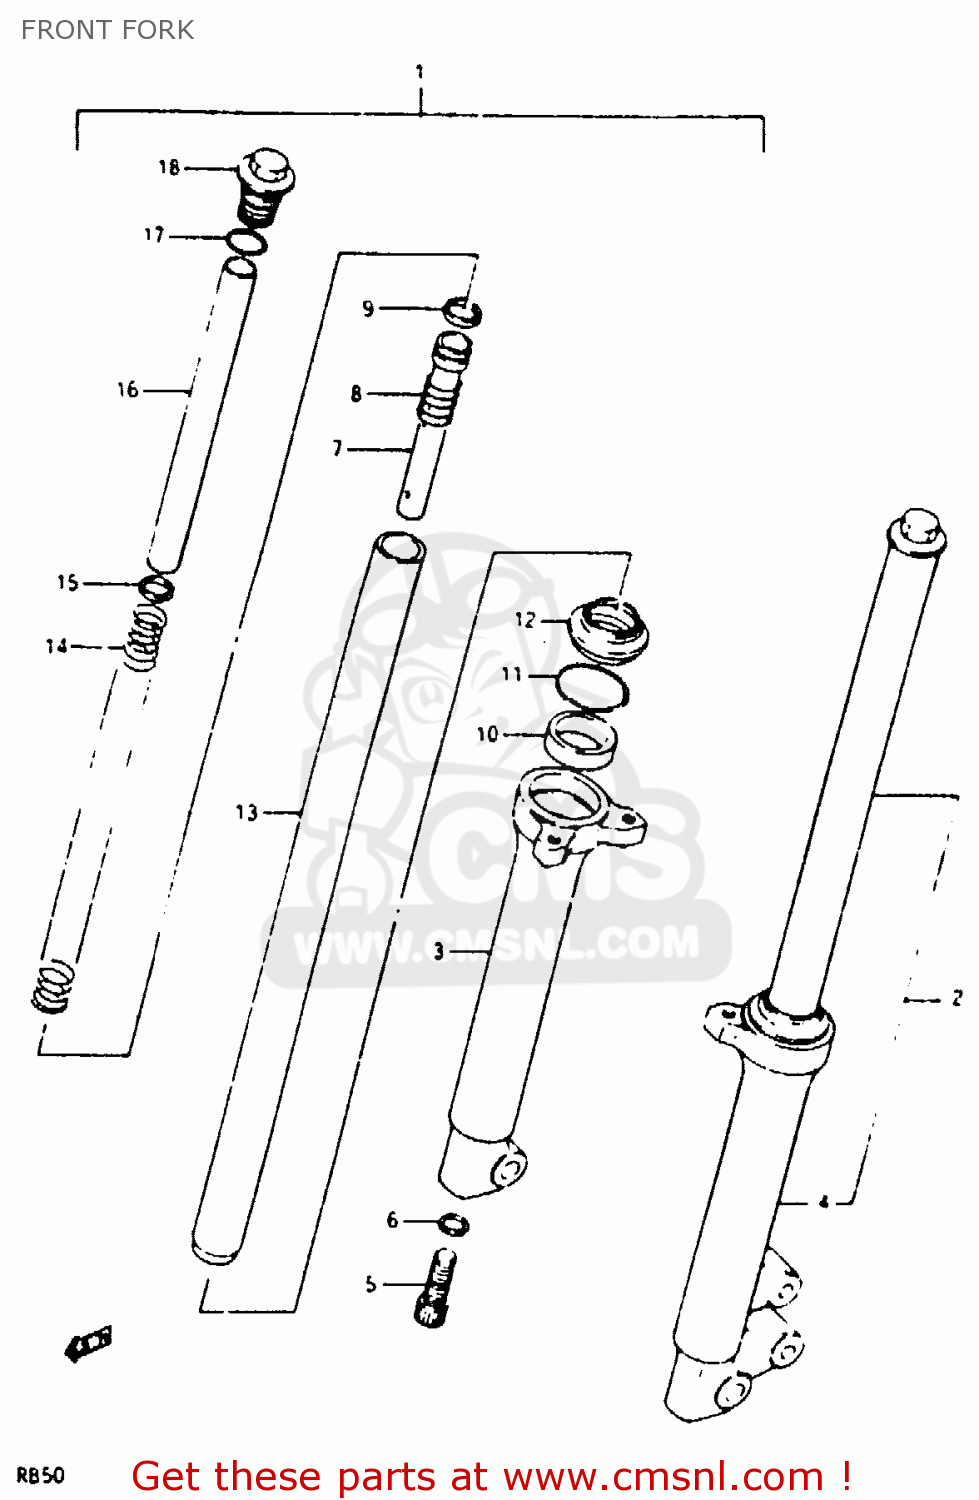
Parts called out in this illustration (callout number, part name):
1	DAMPER ASSEMBLY,RIGHT
2	DAMPER ASSEMBLY,LEFT
3	TUBE,OUTER,RIGHT
4	TUBE,OUTER,LEFT
5	BOLT,FORK CYLINDER(10X25)
6	GASKET (NAS)
7	CYLINDER
8	SPRING,REBOUND
9	RING
10	SEAL,OIL
11	RING,OIL SEAL STOPPER
12	SEAL,DUST
13	TUBE,INNER
14	SPRING
15	WASHER
16	SPACER,FRONT FORK SPRING
17	O-RING,FORK INNER TUBE
18	CAP,FORK INNER TUBE
